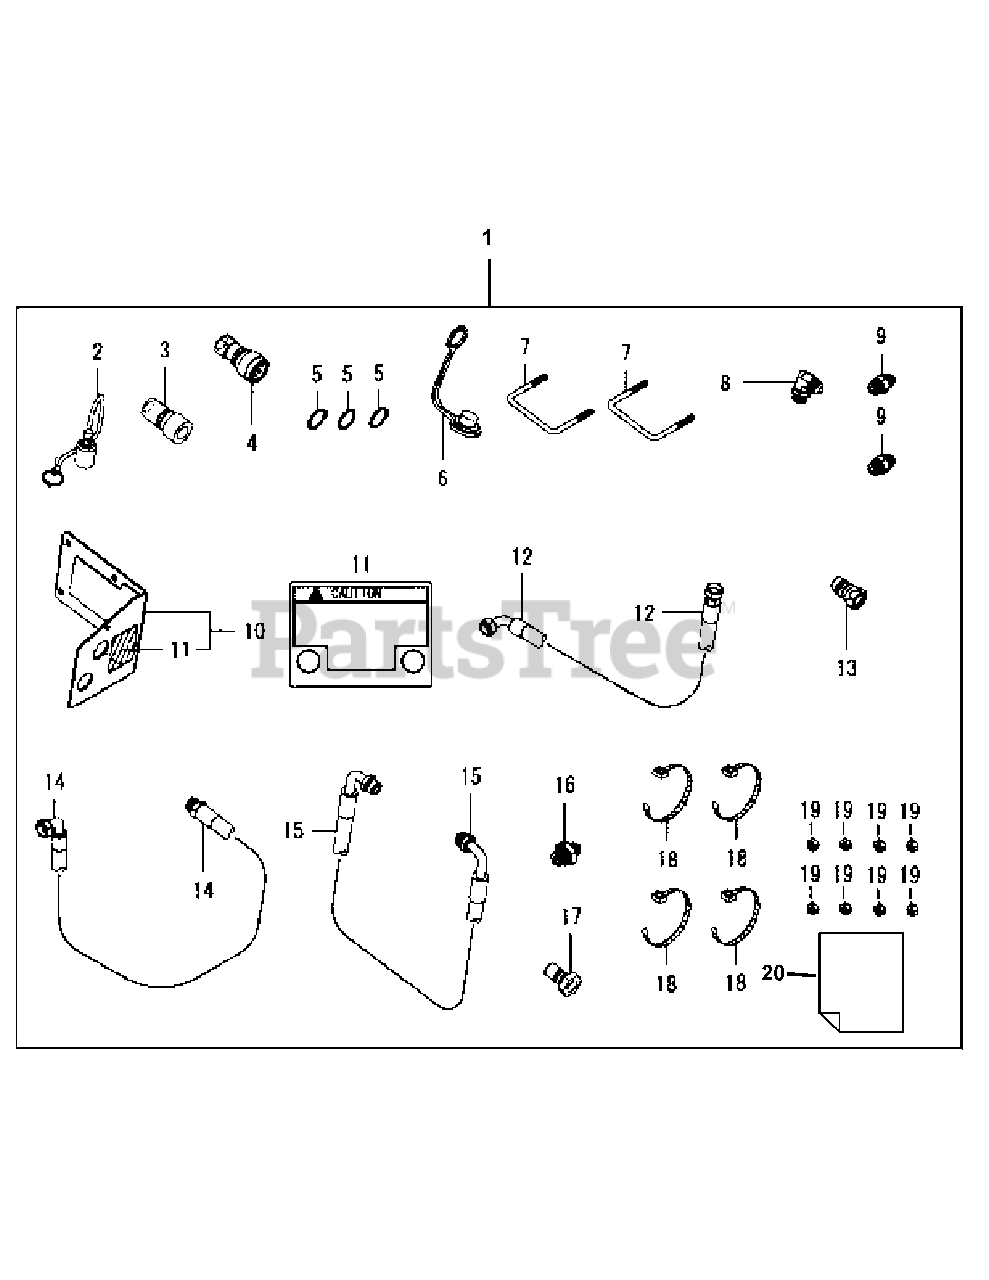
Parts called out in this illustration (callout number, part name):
1	Rear Auxiliary Hydraulic Kit
2	Dust Plug (Yellow)
3	Quick Coupler 3/8 F
4	Quick Coupler 1/2 F
6	Dust Plug (Black)
10	Coupler Bracket Assembly
11	Coupler Bracket Caution Label
12	Hydraulic Hose
13	Quick Coupler 1/2M
14	Hydraulic Hose B
15	Hydraulic Hose C
16	Connector, UNF8 x G 1/2
17	Quick Coupler 3/8 M
20	ASSEMBLY INSTRUCTIONS
